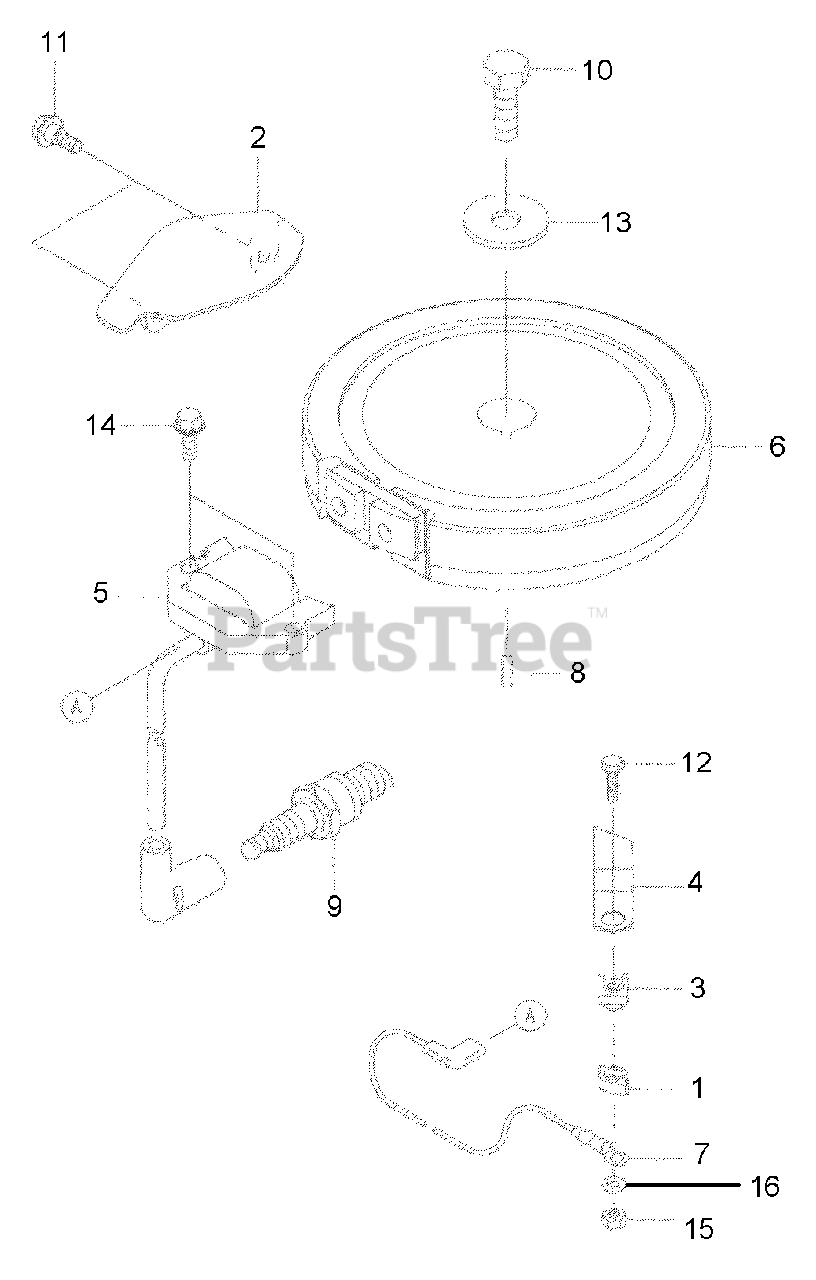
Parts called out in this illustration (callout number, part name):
5	Ignition Coil Assy.
6	Flywheel
9	Spark Plug
10	Bolt, 12x30
14	Flanged Bolt
15	Hex Nut
16	Plain Washer
